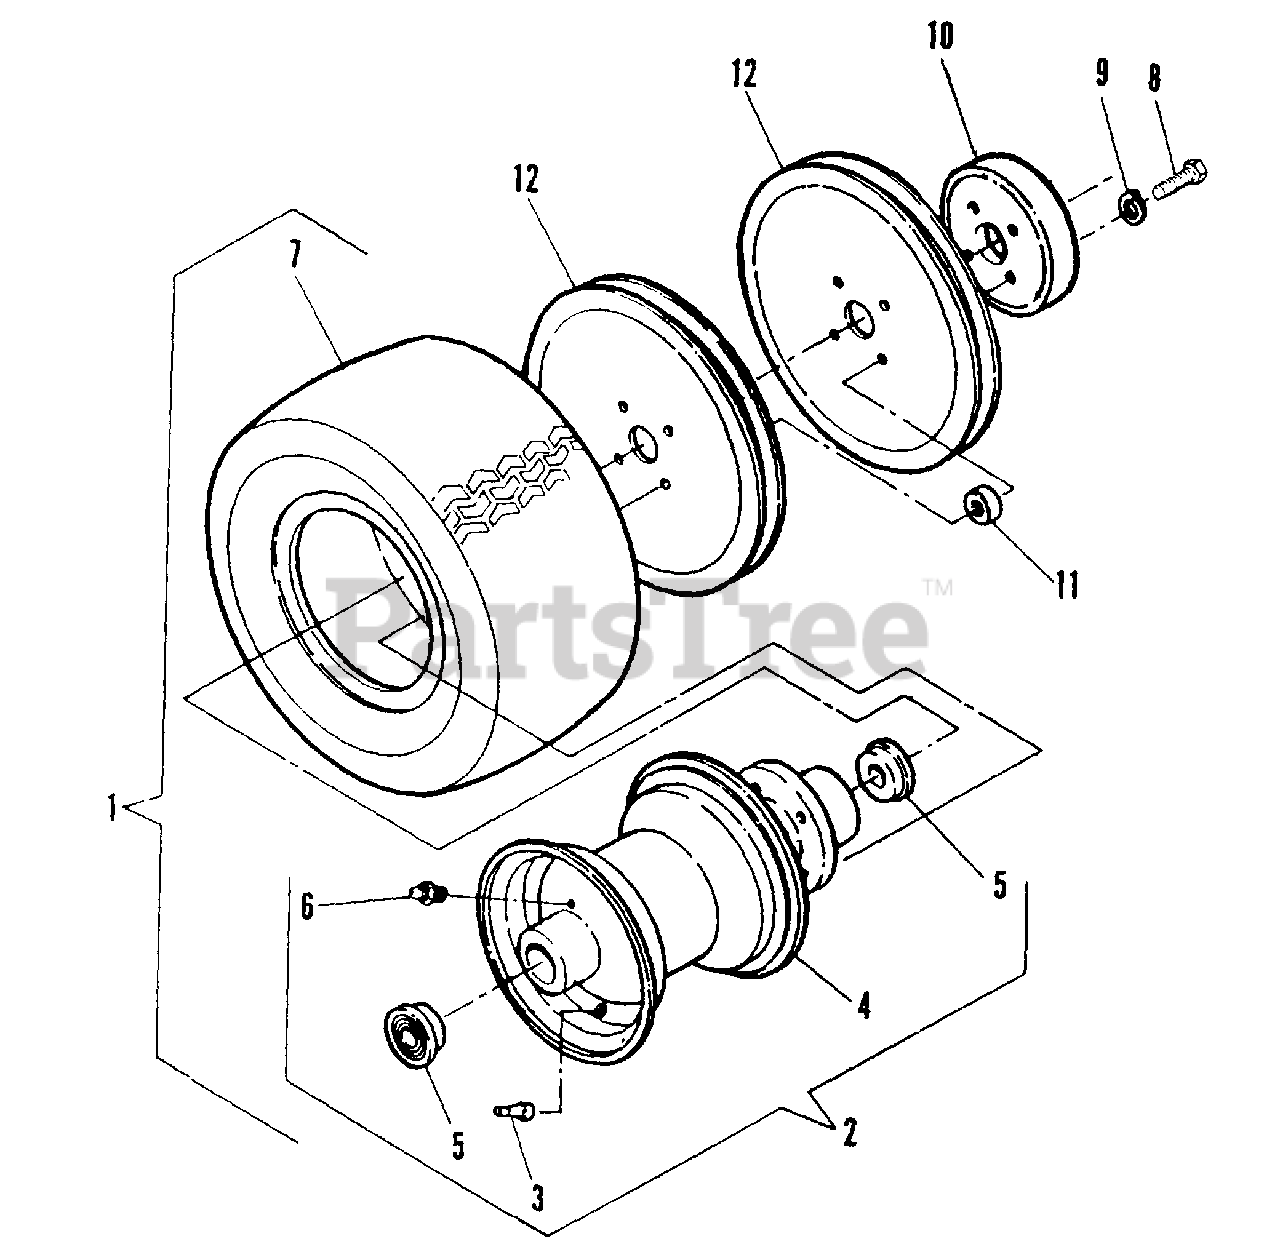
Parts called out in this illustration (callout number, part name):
1	WHEEL & RIM ASSEMBLY
2	RIM ASSEMBLY
3	VALVE STEM
4	RIM
5	BEARING, Wheel
6	ZERK FITTING
7	TIRE, 6.50 x 13 - 6, 2 Ply, Tubeless
8	SCREW, Hex Head Cap, 5/16" - 2 x 1-1/2"
9	WASHER, Lock, 5/16"
10	DRUM, Brake
11	SPACER
12	PULLEY, 8"
